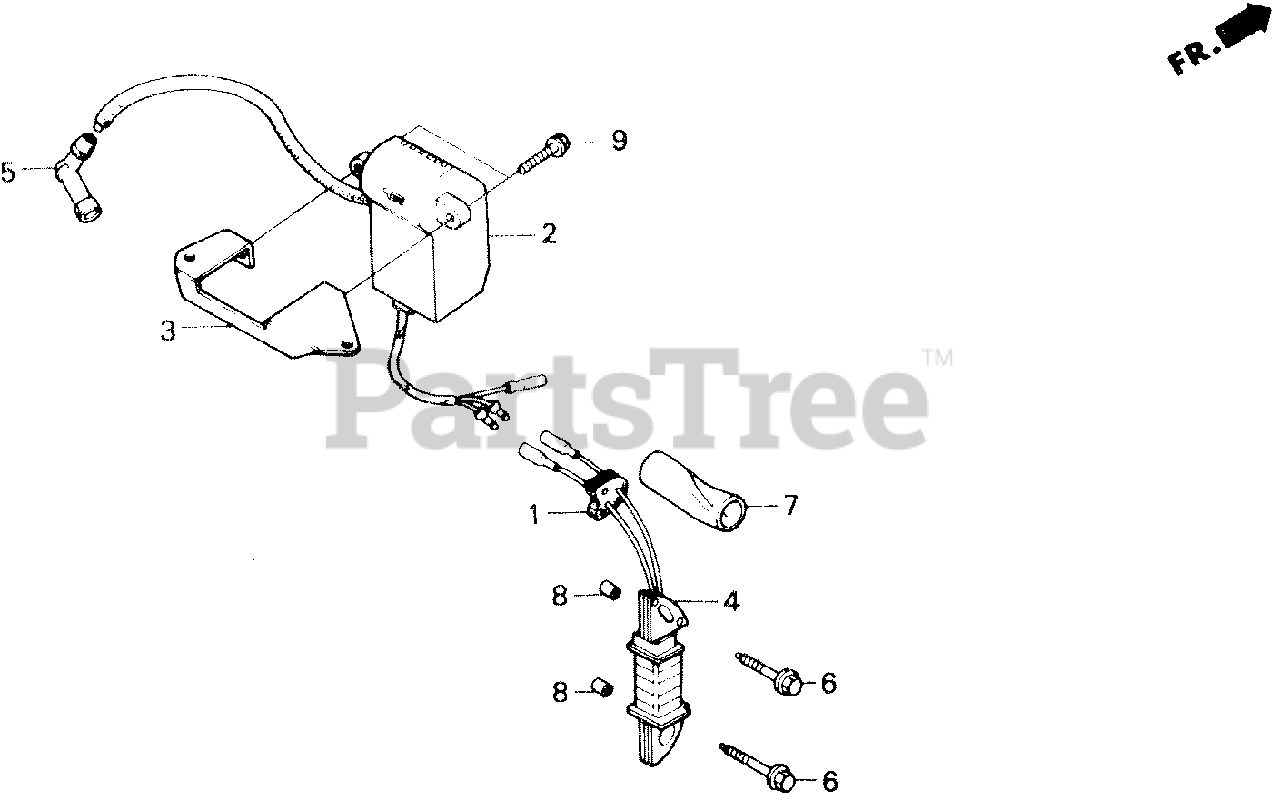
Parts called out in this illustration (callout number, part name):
1	GROMMET, WIRE (C.D.I.)
2	MODULE, IGNITION CONTROL (CDI)
3	STAY, IGNITION CONTROL MODULE (CDI)
4	COIL ASSY., EXCITER
5	TERMINAL ASSY., IGNITION
6	BOLT, FLANGE (6X28) (CT200)
7	TUBE, CORD (B)
8	PIN, DOWEL (8X14)
9	BOLT, FLANGE (6X12)
